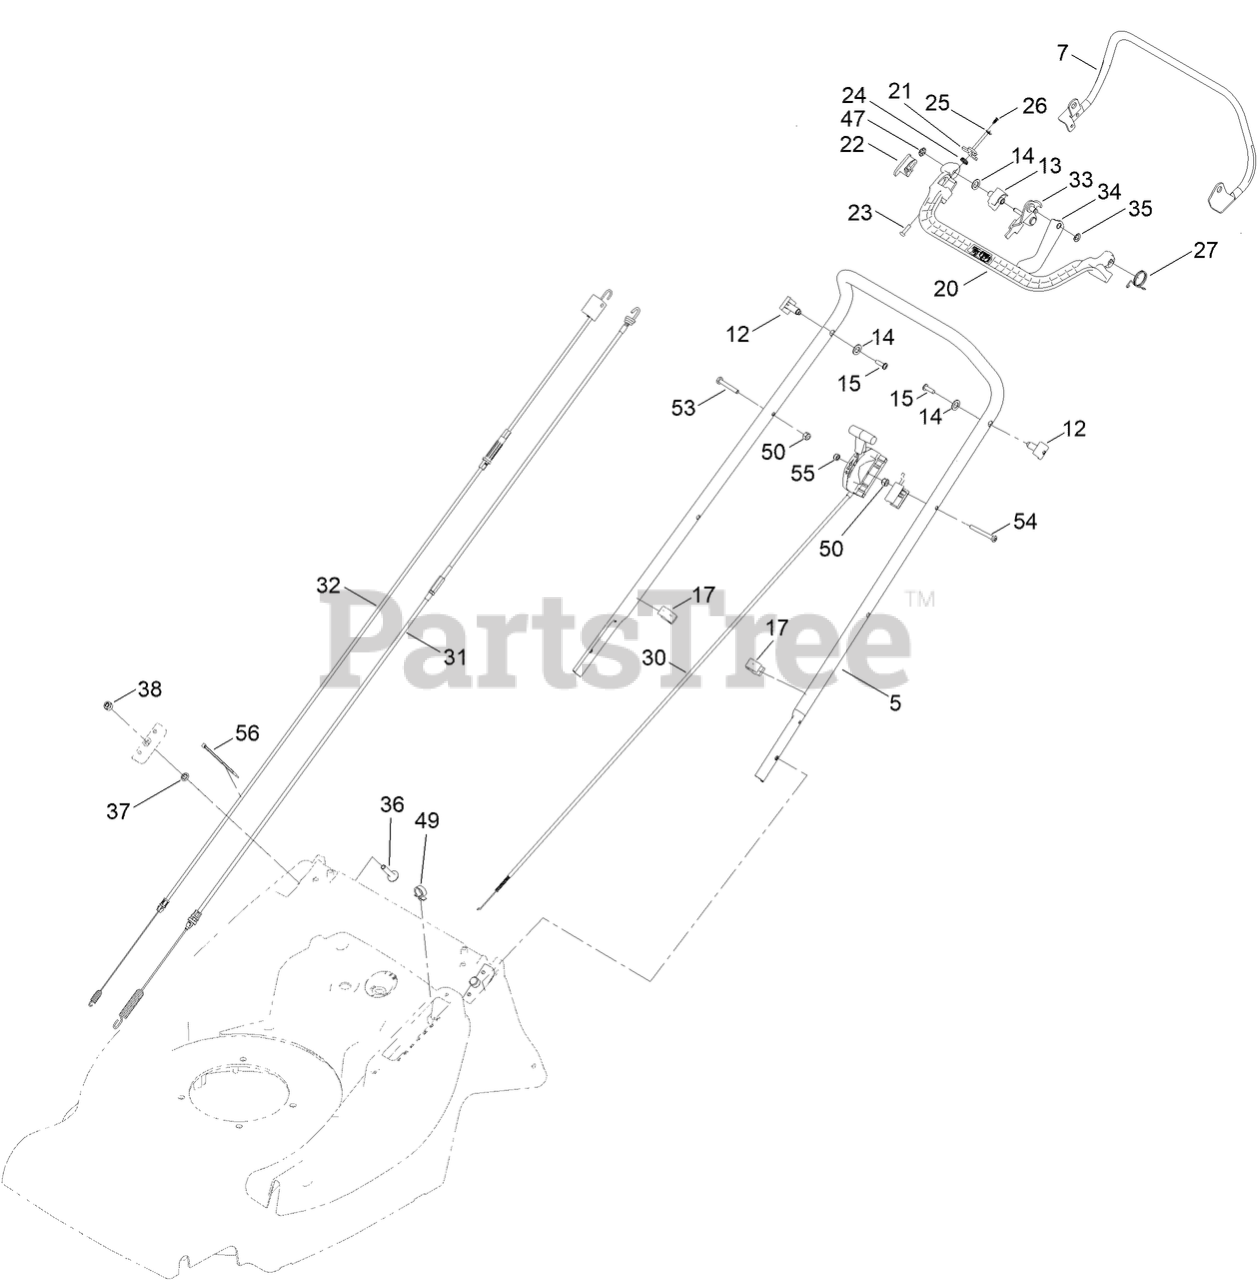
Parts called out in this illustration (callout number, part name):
5	HANDLEBAR-UPPER
7	LEVER-CLUTCH, GEARBOX
12	PIN-PIVOT
13	CLAMP-BAR
14	WASHER-NYLON
15	SCREW
17	GUIDE-CABLE
20	ARM-BAIL
21	LEVER-CATCH
22	LATCH-BUTTON
23	LATCH-PIN
24	LEVER-BAIL, SPRING
25	FASTENER-STARLOCK, PUSH-ON
26	CLIP-TREE
27	LEVER-BAIL ARM, SPRING
30	THROTTLE-CONTROL
32	CLUTCH-CABLE, 3 SPEED
33	LEVER-CABLE
34	LINKAGE PLATE ASSEMBLY
35	WASHER-STARLOCK
36	BOLT-COACH
37	GRIP-FIX
38	NUT-HEX, NI
47	STARLOCK-DOMED
49	CLIP-CONDUIT, TWIN
50	NUT-HEX
53	BOLT
54	SETSCREW
55	NUT-NYLOC
56	TIE-CABLE
